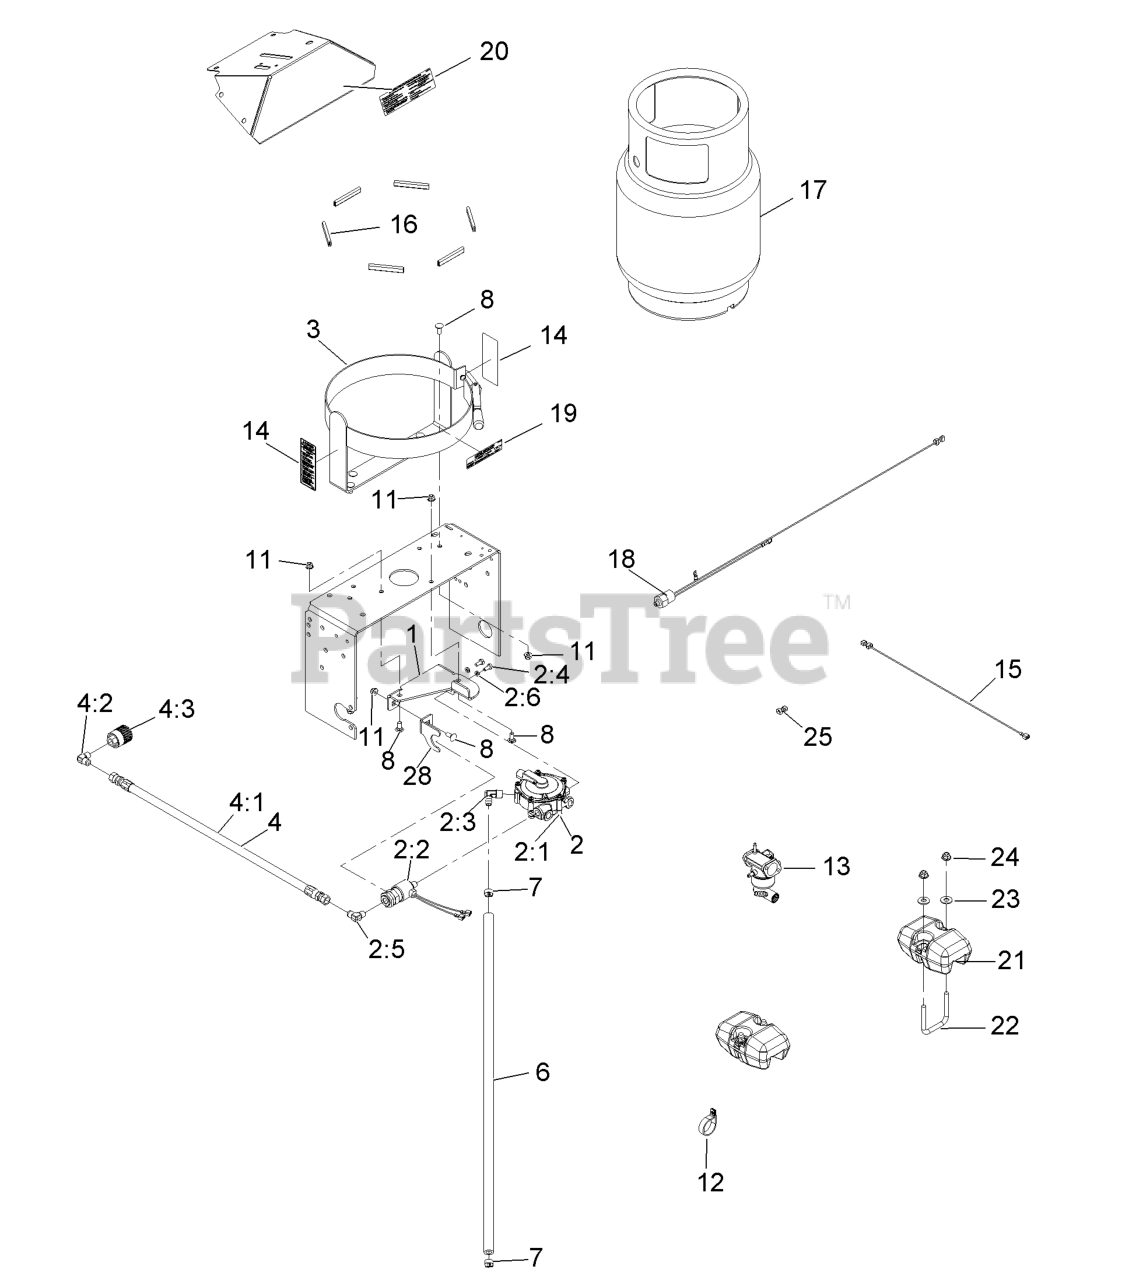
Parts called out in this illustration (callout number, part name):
1	REGULATOR MOUNT-THP
2	Asm, Reg And Shutoff
2:1	Regulator-Lp, T60
2:2	ASM, LPG FUEL SHUTOFF W/T
2:3	ELBOW-90 DEG
2:4	SCREW-HH
2:5	ELBOW 90DEG,1/4 NPT X3/8
2:6	WASHER-LOCK
4	Asm, Lpg Fuel Hose
4:2	ELBOW 90DEG,1/4 NPT X3/8
4:3	CONNECTOR-LPG TANK, LH TH
6	HOSE,LP 1/2 X 33
7	CLAMP-HOSE
8	BOLT-CARR
11	NUT-HF, NI
12	CLIP-LOOM
13	MIXER ASM, KA FS600V
14	DECAL-LPG WARNING
15	ASM, WIRE 20"
16	STRIP-SEAL
19	DECAL,LPG TANK SPEC VERTI
20	DECAL-TANK REPLACEMENT
21	WEIGHT-SUPPORT, CASTER
23	WASHER-FLAT
24	NUT-HF, NI
25	RECEPTICAL -FEM, .250, IN
28	SOLENOID SUPPORT
